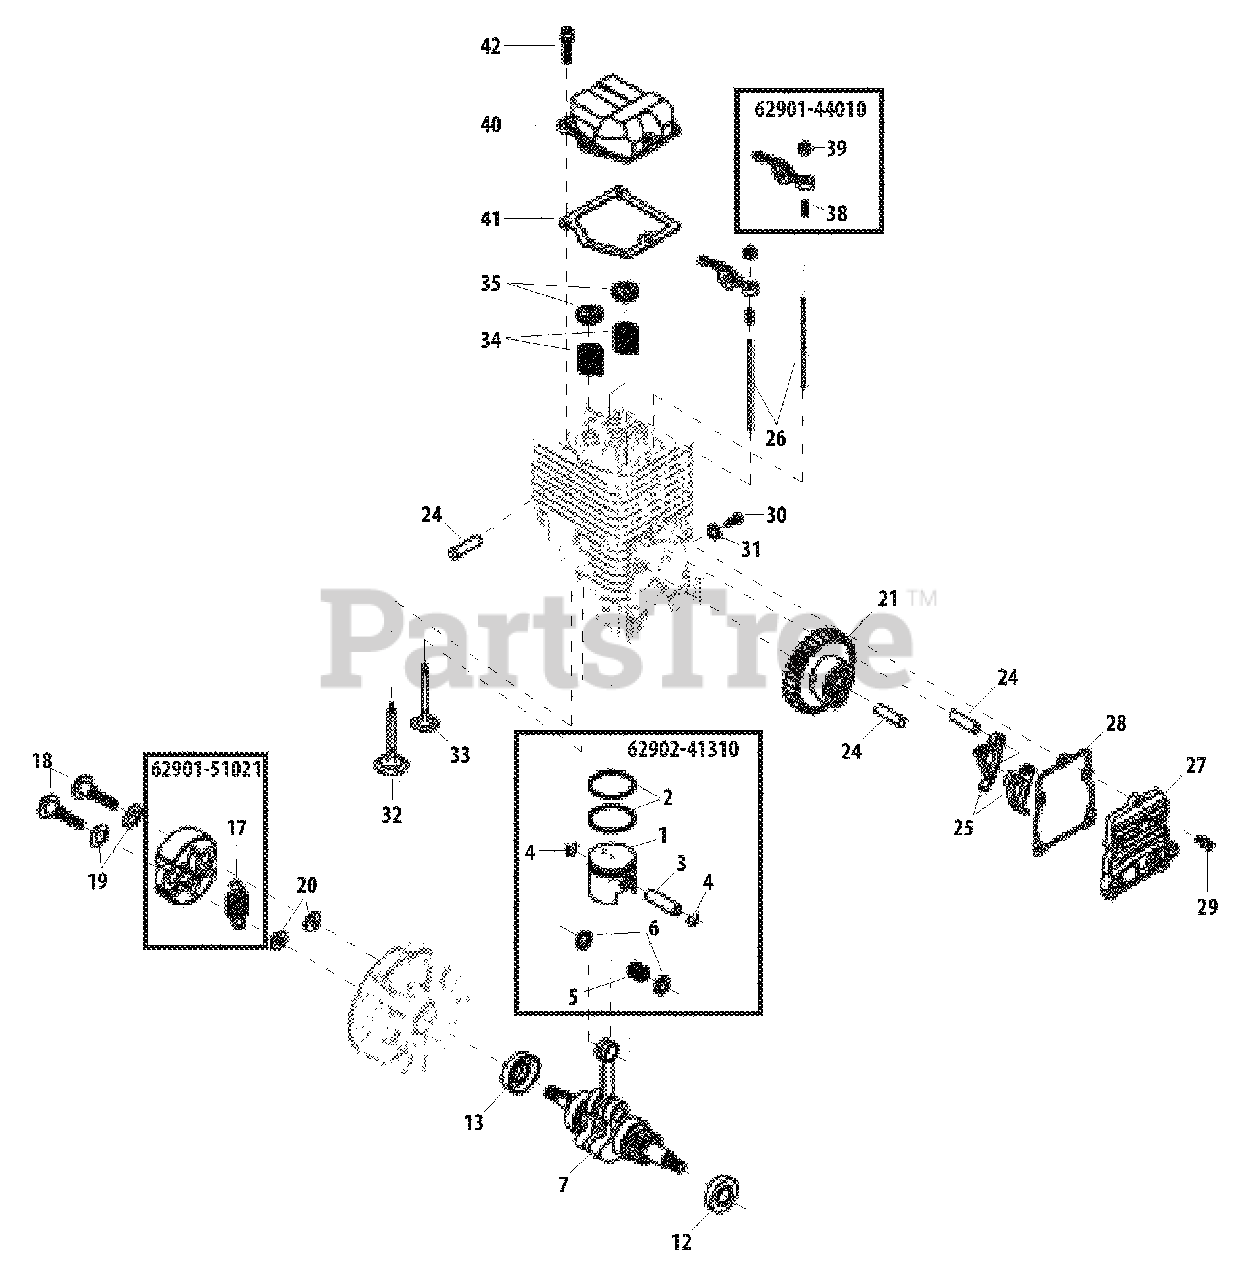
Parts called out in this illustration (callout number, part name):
1	PISTON
2	RING, PISTON
3	PIN, PISTON
4	RING, RETAINING
5	BEARING, NEEDLE
6	SPACER - 9
7	CRANKSHAFT ASSY
12	SEAL, OIL - 12
13	SEAL, OIL - 12
17	SPRING, CLUTCH
18	BOLT, CLUTCH
19	WASHER - SPRING
20	WASHER - 6
21	GEAR, CAM
24	PIN - LOCATING
25	FOLLOWER, CAM
26	PUSHROD
27	COVER, CAM GEAR
28	GASKET
29	SCREW - 4X14
30	SCREW - 5
31	WASHER
32	VALVE, INTAKE
33	VALVE, EXHAUST
34	SPRING, VALVE
35	VALVE RETAINER ASSY
38	SCREW, ADJUST
39	LOCKNUT, ADJUSTER
40	COVER, ROCKER ARM
41	GASKET
42	SCREW - 4X14
62901-44010	ROCKER ARM ASSY
62901-51021	CLUTCH ASSY
62902-41310	PISTON KIT
